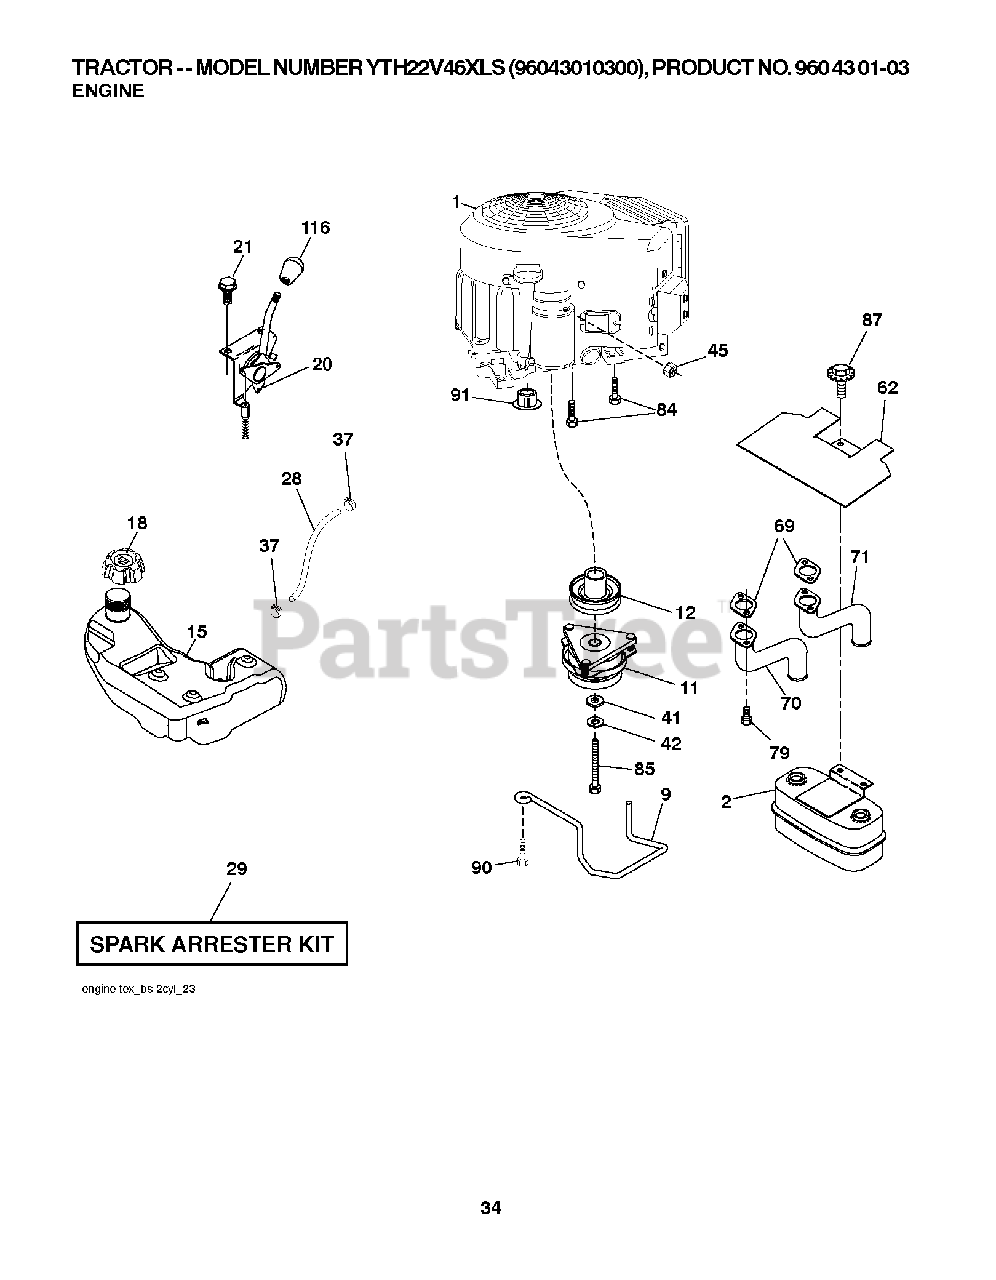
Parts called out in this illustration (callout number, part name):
1	Husqvarna TBD
2	MUFFLER.TWIN.CYL.LOW.TONE
9	KEEPER.BELT.ENGINE.4.2
11	CLUTCH.ELECTRIC.LT.48"*
12	PULLEY.ENGINE.TUFFTORQ
15	TANK.ASSY.3.GAL.EPA
18	CAP.ASM.FL.RITCH.3"E10.SYM.498
20	CONTROL THROTTLE/CHOKE
21	SCREW.#10 X 0.750.BOS
28	LINE.FUEL.64"REAR.EMIS
29	KIT.SPARK ARRESTOR 794945 B&S
37	HOSE CLAMP
42	LOCKWASHER
45	NUT
62	SHIELD.HEAT.MUFFLER
69	GASKET.MUFFLER
70	RP.EXHAUST.TUBE.LH.BS/TWIN
71	EXHAUST.TUBE.RH.BS/TWIN
79	SCREW.SOCKET.HEAD.5/16-18
84	SCREW.3/8-16
85	BOLT HEX 7/16-20X4-1/4"
87	Bolt, 5/16-18 X 1-3/4
90	SCREW 3/8-16X1
91	BUSHING.1.375OD
116	RP KNOB SOFT TOUCH
